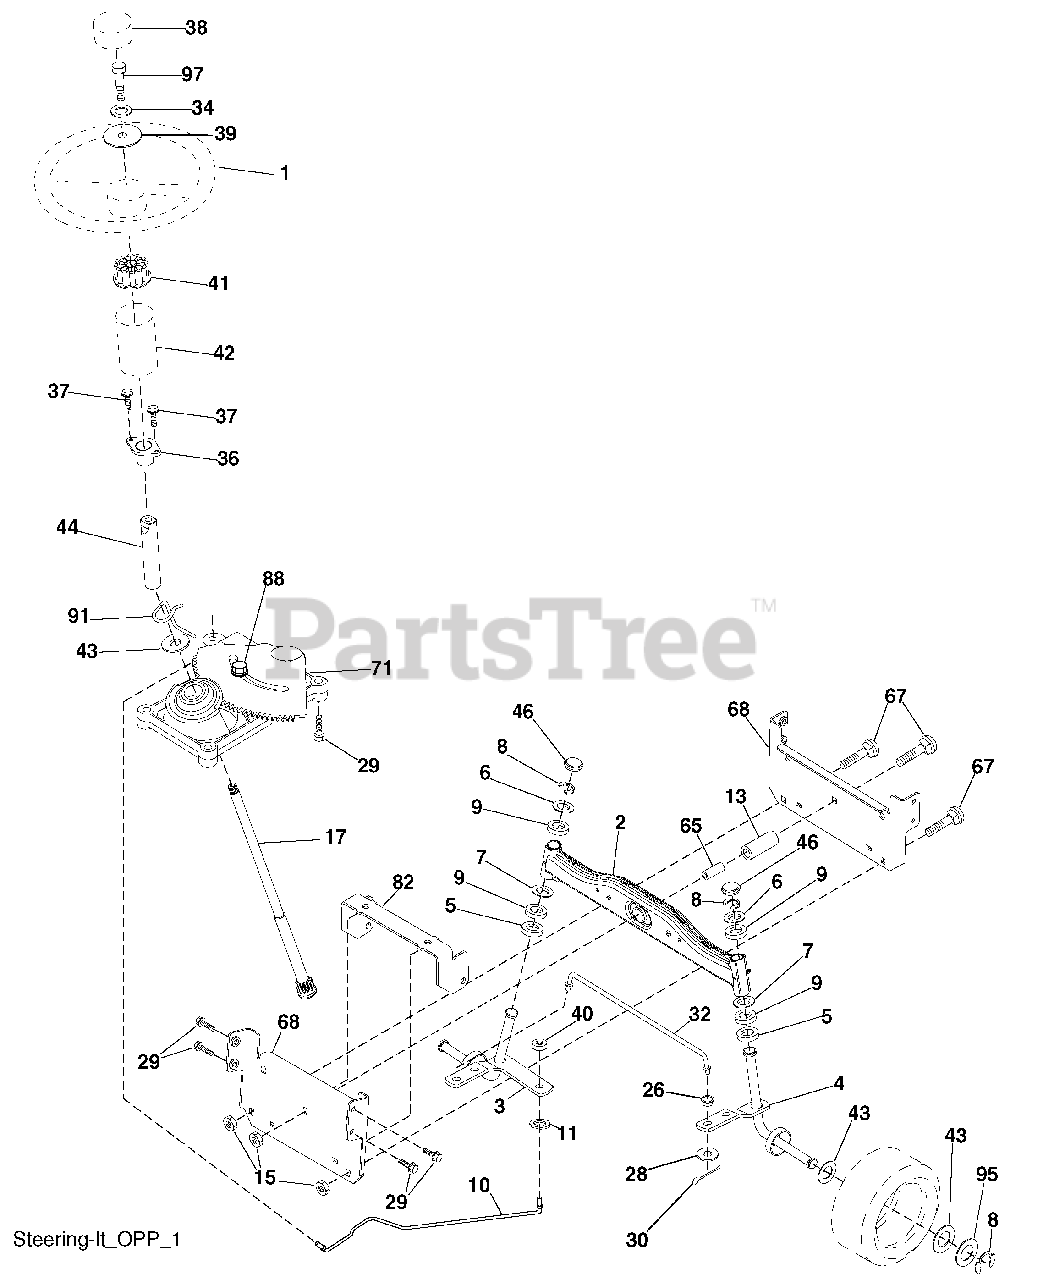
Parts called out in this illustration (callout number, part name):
1	Wheel Steering
2	Axle Asm
3	Spindle Asm LH
4	Spindle Asm RH
5	Bearing Race Thrust Harden
6	Washer 25/32 x 1-5/8 x 16 Ga.
7	Washer 27/32 x 1-1/4 x 16 Ga.
8	Ring Klip #t5304-75
9	Bearing Col Strg Blk
10	Link Drag
11	Washer Lock Hvy Hlcl Spr 3/8
13	Spacer Brace Axle
15	Hexflange Lock
17	Shaft Asm Strg
26	Bushing Link Drag Blk LR
28	Washer 13/32 x 7/8 x 16 Ga.
29	Screw 3/8-16 x 3/4
30	Pin Cotter 11/32 ID x 2 3/8 OD x 12 Ga.
32	Rod Tie Wire Form 19 75 Mech
34	Washer Lock 5/16
36	Bushing Strg 5/8 Id Dash
37	Screw
38	Cap Wheel Steer
39	Washer 11/32 x 2 3/8 OD x 12 Ga.
40	Nut Crownlock 3/8-24
41	Adaptor Wheel Strg
42	Boot Dash Mtl Steering Blk
43	Washer 25/32 x 1 1/4 x 16 Ga.
44	Extension Steering
46	Cap Spindle Fr Top Blk
65	Spacer Brace Axle
67	Bolt RDHD SQNK 3/8-16 x 2-1/4
68	Brace Axle
71	Steering Asm.
82	Bracket Susp Chassis Front
88	Bolt Shoulder 7/16-20
91	Clip Steering
95	Washer Harden .793 x 1.637 x 060
97	Bolt 5/16-18 x 4 Gr.5
